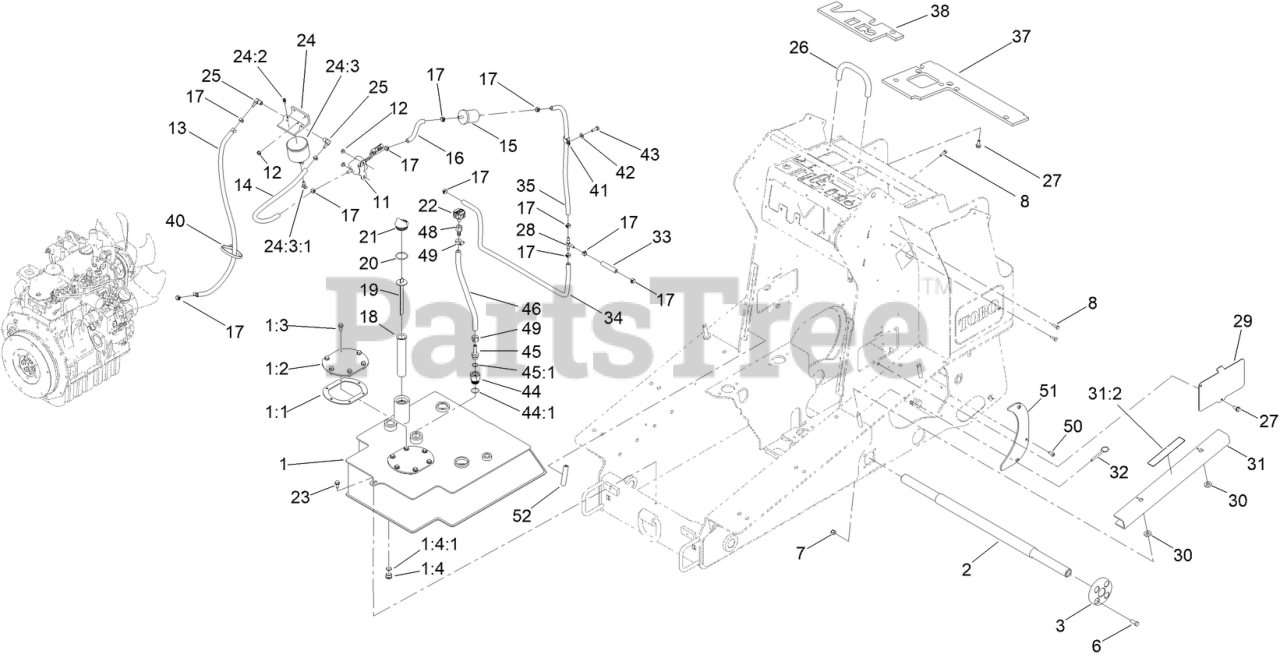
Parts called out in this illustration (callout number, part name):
1	TANK-HYD
1:1	GASKET-COVER, ACCESS
1:2	COVER-TANK
1:3	SCREW-HHF
1:4	PLUG-HEX
1:4:1	O-RING
2	SHAFT-TRACK
3	HUB-SHAFT
6	SCREW-HH
7	NUT-LOCK, NI
8	SCREW-HH
11	PUMP-FUEL, ELECTRIC
12	NUT-HF
13	HOSE-FUEL
14	HOSE-FUEL
15	FILTER-FUEL
16	HOSE-FUEL
17	CLAMP-HOSE
18	FILTER-SCREEN
19	DIPSTICK
20	O-RING
21	PLUG-PLASTIC
22	BREATHER
23	SCREW-THD ROLL, HWH
24	FILTER HEAD ASM
24:2	VENT-AIR
24:3	ELEMENT-SPIN ON
24:3:1	VALVE-DRAIN
25	FITTING-HYD, 90
26	BAR-REFERENCE
27	SCREW-HHF
28	FITTING-TEE, BARBED
29	PLATE-COVER, ACCESS
30	WASHER-NEOPRENE
31	ARM-LOCKING
31:2	DECAL-DANGER
32	PIN-COTTERLESS
33	HOSE-FUEL
34	HOSE-FUEL
35	HOSE-FUEL
37	FOAM-HEAT SHIELD
38	FOAM-HEAT SHIELD
40	TIE-CABLE
41	CLAMP-R
42	WASHER-FLAT
43	SCREW-HH
44	FITTING-STRAIGHT
44:1	O-RING
45	FITTING-STR
45:1	O-RING
48	FITTING-FEMALE, BARBED
49	CLAMP-HOSE
50	PLATE-DIRT
51	SCREW-BHTF
